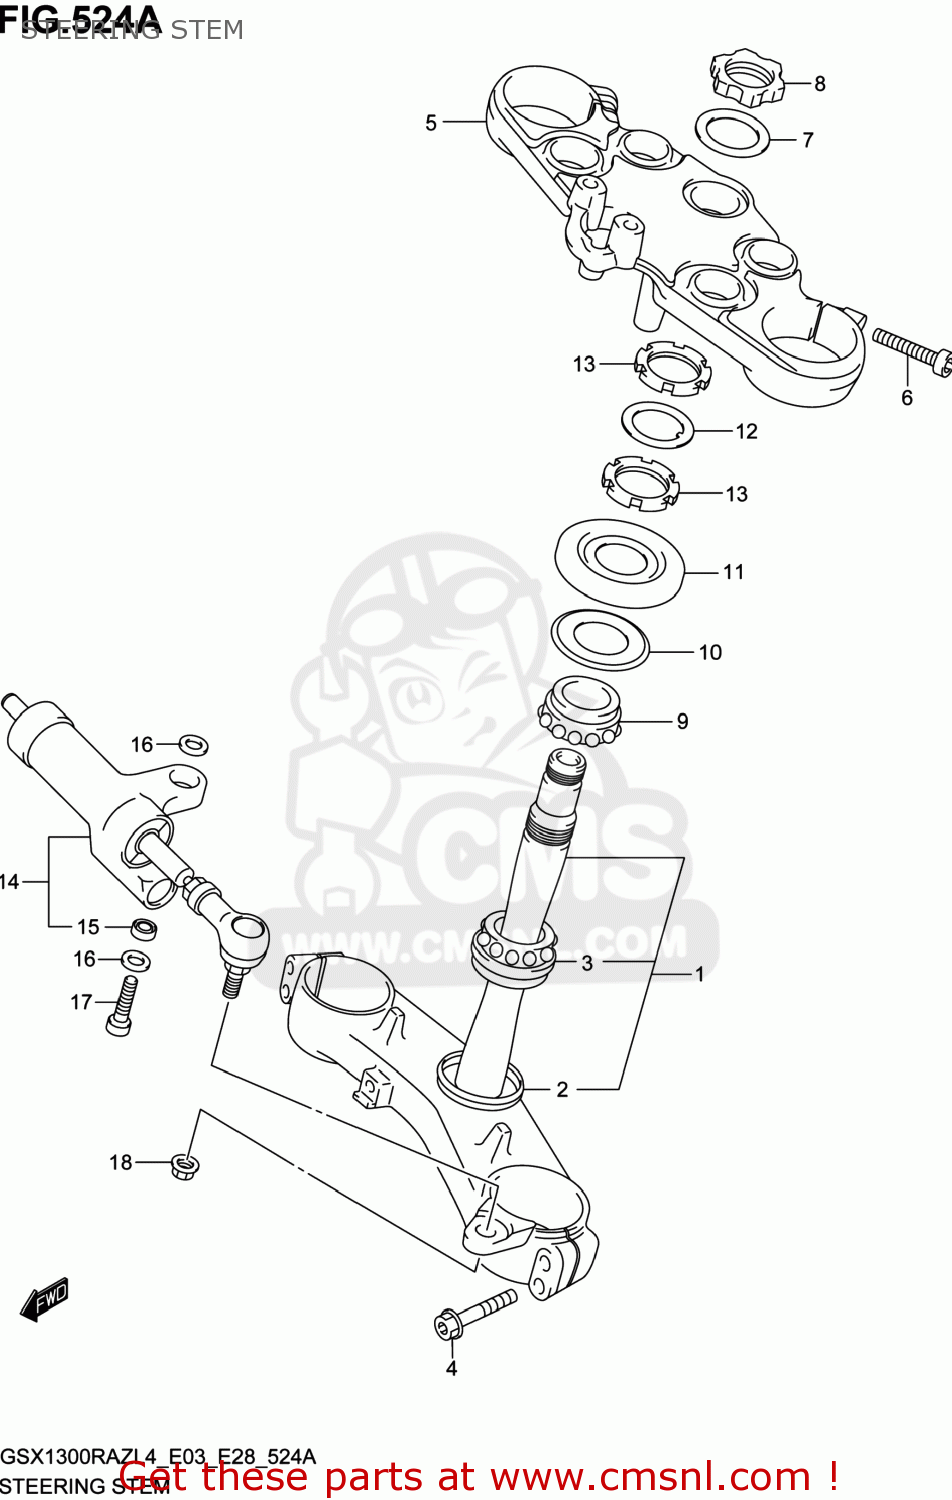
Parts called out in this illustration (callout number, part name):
1	BRACKET,FR FORK UNDER
2	SEAL,STEERING LWR
3	BEARING(30X55X17)
4	BOLT,AXLE STOPPER
5	BRACKET,FR FORK UPR
6	BOLT
7	WASHER
8	NUT
9	BEARING(30X55X17)
10	SEAL,STEERING LWR
11	COVER,STEERING UPR
12	WASHER,STEERING STEM
13	NUT,STEERING STEM
14	DAMPER ASSY,STEERING
15	BEARING(8X17.5X11)
16	SEAL,PILLOW BALL,DUST
17	BOLT
18	NUT
